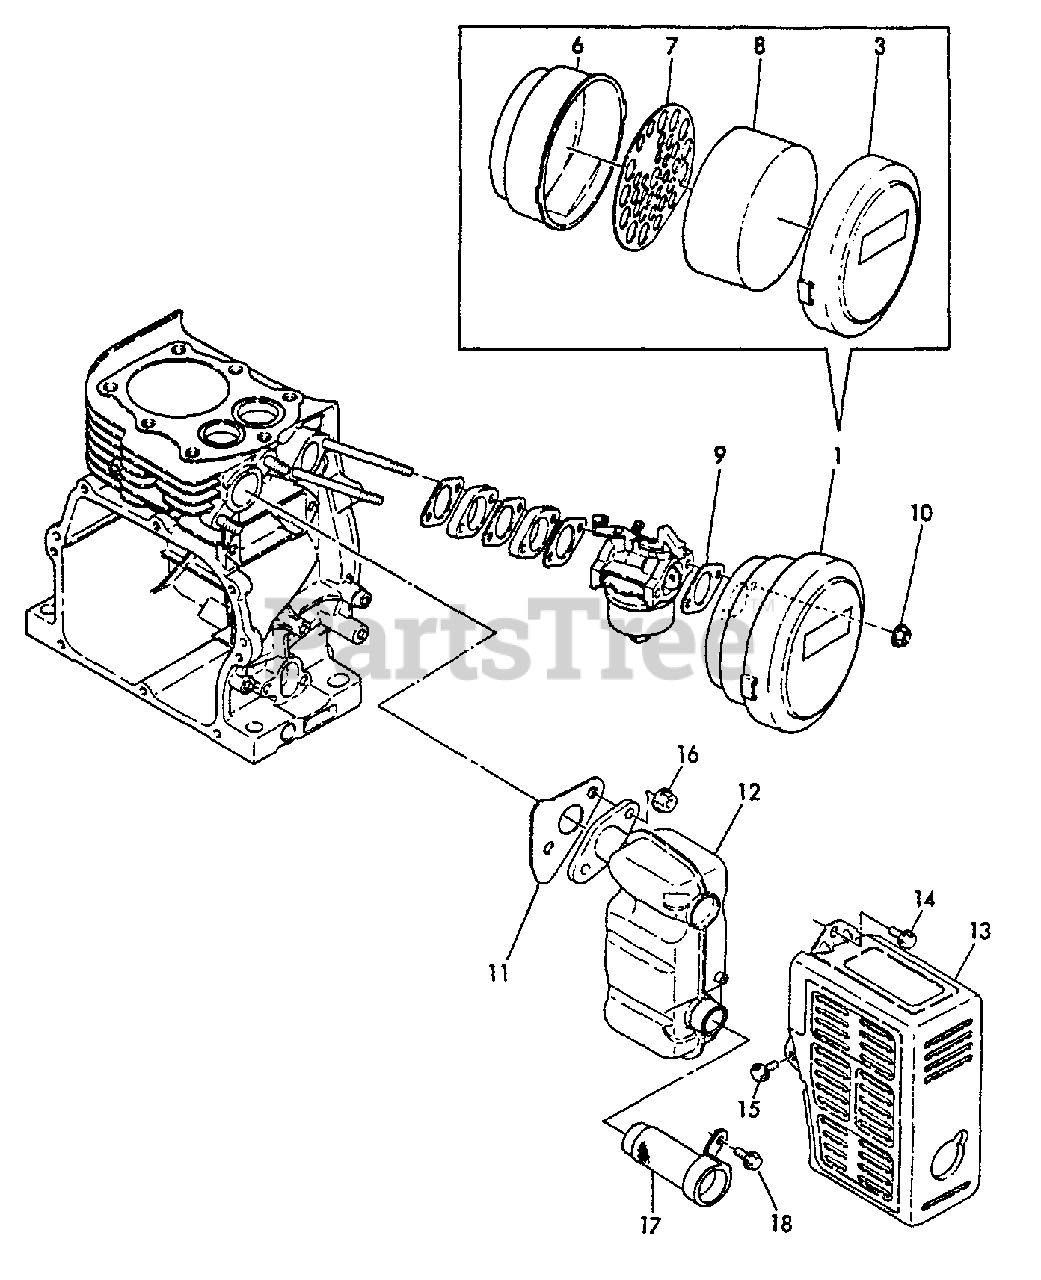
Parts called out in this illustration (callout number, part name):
1	AIR CLEANER ASSY
3	COVER, AIR FILTER
6	CASE, AIR FILTER
7	PLATE, ELEMENT
8	FILTER, AIR
9	GASKET, INTAKE
10	NUT - 6 -- FLANGE
11	GASKET, EXHAUST
12	MUFFLER
13	COVER, MUFFLER
14	BOLT - 6X12 -- PLATED
15	BOLT - 6X8 -- PLATED
16	NUT - 8
17	SCREEN, SPARK ARRESTOR
18	BOLT - 6X10 -- PLATED
